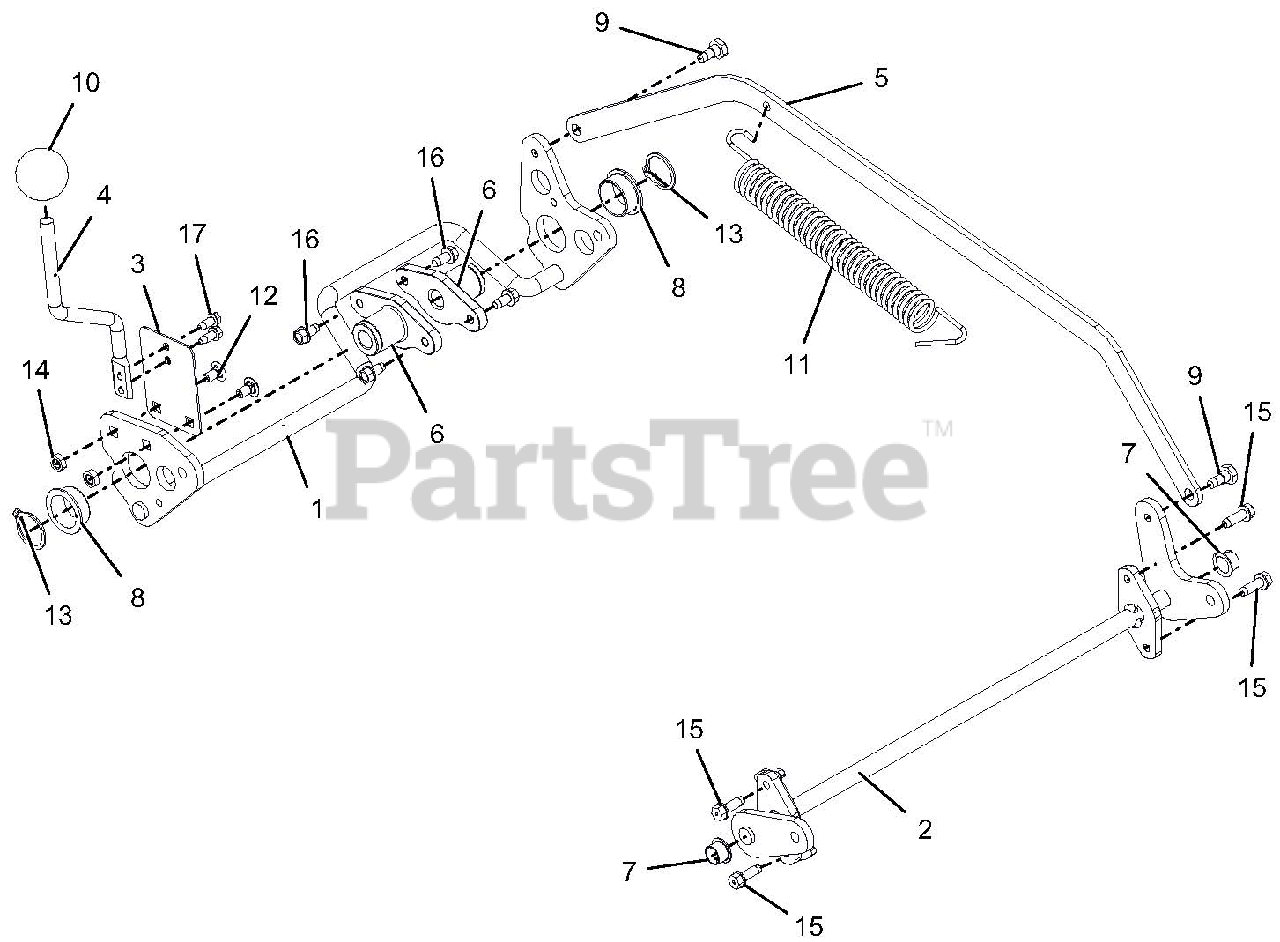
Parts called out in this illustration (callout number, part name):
1	WLDMT, REAR AXLE
2	WMT, LM FRONT AXLE
3	PLATE, HOC SPRING
4	LEVER, HOC ADJUSTMENT
5	LINKAGE, HOC CONNECT
6	HUB, LM REAR AXLE
7	BUSHING, POLYLINER-.50 SPLIT
8	BSHG-FLG 1.0X1.125X.50X1.375 R
9	BOLT, SHLDR .320X.210X.25-20
10	KNOB,BALL -BLACK 1.47" .375-16
11	SG-TENS .121X1.00X6.5 WLD
12	@BLT-RDHDSQNK .25-20X.50 G5YZ
13	RG-RTNG-EXT 1.00X.042
14	NUT-LK-CTR JAM .25-20 YWZC
15	SCR-TAP-PM .25-20X.75 TR YWZ
16	SCR-TAP .25-20X.50 HWH TR YWZ
17	@SCR-TAP 12-24X.50 HWH TR YWZC
